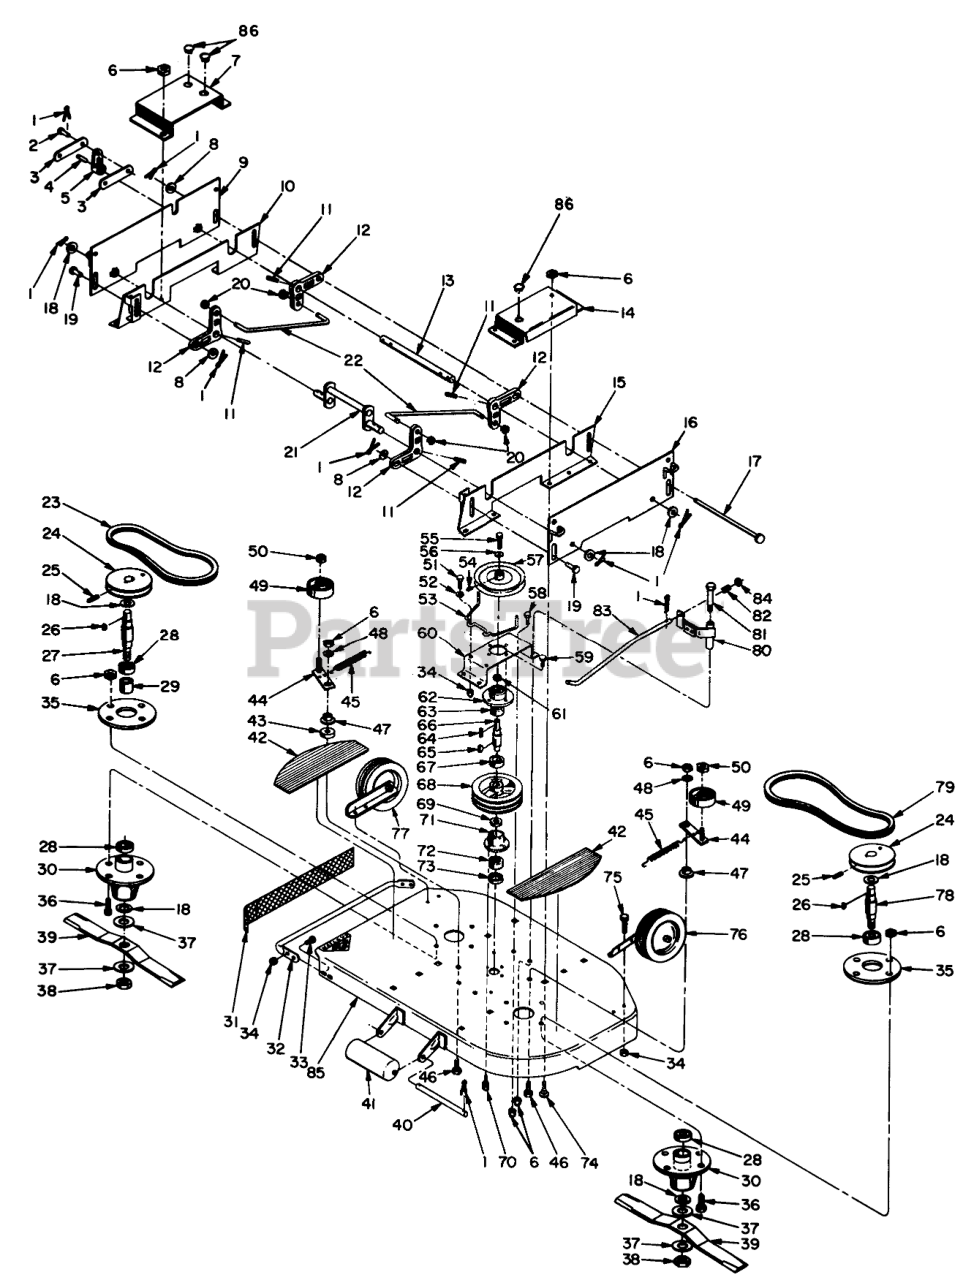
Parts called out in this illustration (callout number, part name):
1	PIN-COTTER
2	Pin
3	Lift Link
5	Lever
7	Pulley Cover, R.H.
8	Washer
9	Mower Bracket, R.H.
10	Lower Bracket, R.H.
11	Roll Pin
12	Bell Crank
13	Pivot Shaft, Rear
14	Pulley Cover, L.H.
15	Lower Bracket, L.H.
16	Mower Bracket, L.H.
17	Lift Shaft
18	WASHER
19	Lift Pin
20	RING-RETAINING, EXT
21	Lift Shaft, Front
22	Lift Link
23	Belt, Right Hand
24	Pulley
25	Set Screw
26	KEY-WOODRUFF
27	Blade Shaft
28	Bearing
29	Spacer
30	Spindle Housing
31	Mulcher
32	Blade Guard
33	SCREW-CARR
35	Washer
36	SCREW-HH
37	WASHER
38	Nut
39	Blade
40	ROLLER SHAFT
41	Roller
42	Footpad
43	Spacer
44	Idler Bracket
45	IDLER ARM SPRING
46	SCREW-HH
47	Bushing
48	WASHER-FLAT
49	PULLEY IDLER
50	NUT-JAM
51	SCREW-HH
52	WASHER-FLAT
53	Belt Guide
54	SCREW-SET
55	SCREW-HH
56	Washer
57	Pulley
58	SCREW-HH
59	Sems Unit
60	Support
61	Washer
62	Bearing Housing
63	Bearing
64	KEY-SQUARE
65	KEY-WOODRUFF
66	BLADE DRIVE SHAFT
68	Pulley
69	Washer
70	Sems Unit
71	Housing
72	Bearing
73	Spacer
74	Screw
75	SCREW-HH
76	Wheel Assembly, L.H (Consists of)
77	Wheel Assembly, R.H. (Consists of)
78	Blade Shaft
80	Brake Band (Consists of)
81	Shoulder Bolt
82	Spring
83	Brake Rod
84	Washer
85	Mower Housing
86	Button Plug
